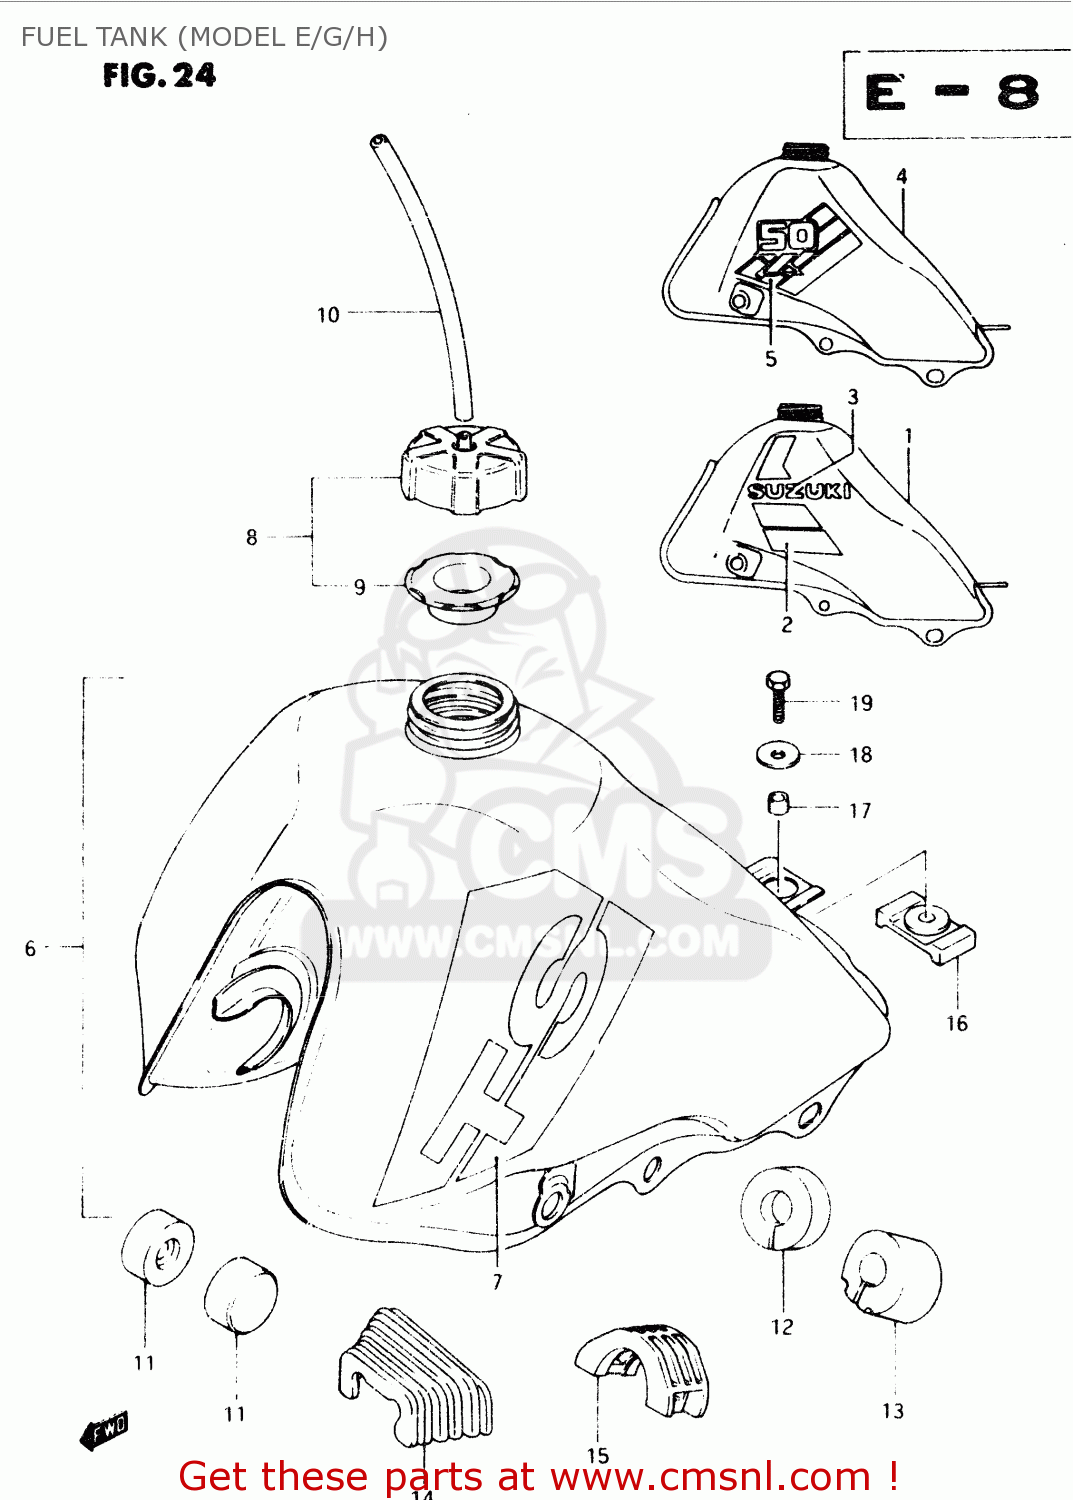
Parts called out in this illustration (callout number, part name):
1	TANK ASSY, FUEL (RED)
2	TAPE SET, FUEL TANK
3	EMBLEM(WHITE)
4	TANK ASSY,FUEL
5	TAPE SET, FUEL TANK
6	TANK ASSY,FUEL
7	TAPE SET, FUEL TANK
8	CAP SET,FUEL TANK
9	GASKET (NAS)
10	HOSE
11	CUSHION
12	CUSHION, LOWER RH
13	CUSHION
14	CUSHION,FUEL TANK LWR
15	CUSHION,FUEL TANK CTR
16	CUSHION,FUEL TANK RR
17	SPACER (6.1X9X9)
18	WASHER(6.5X20X1.6)
19	BOLT
